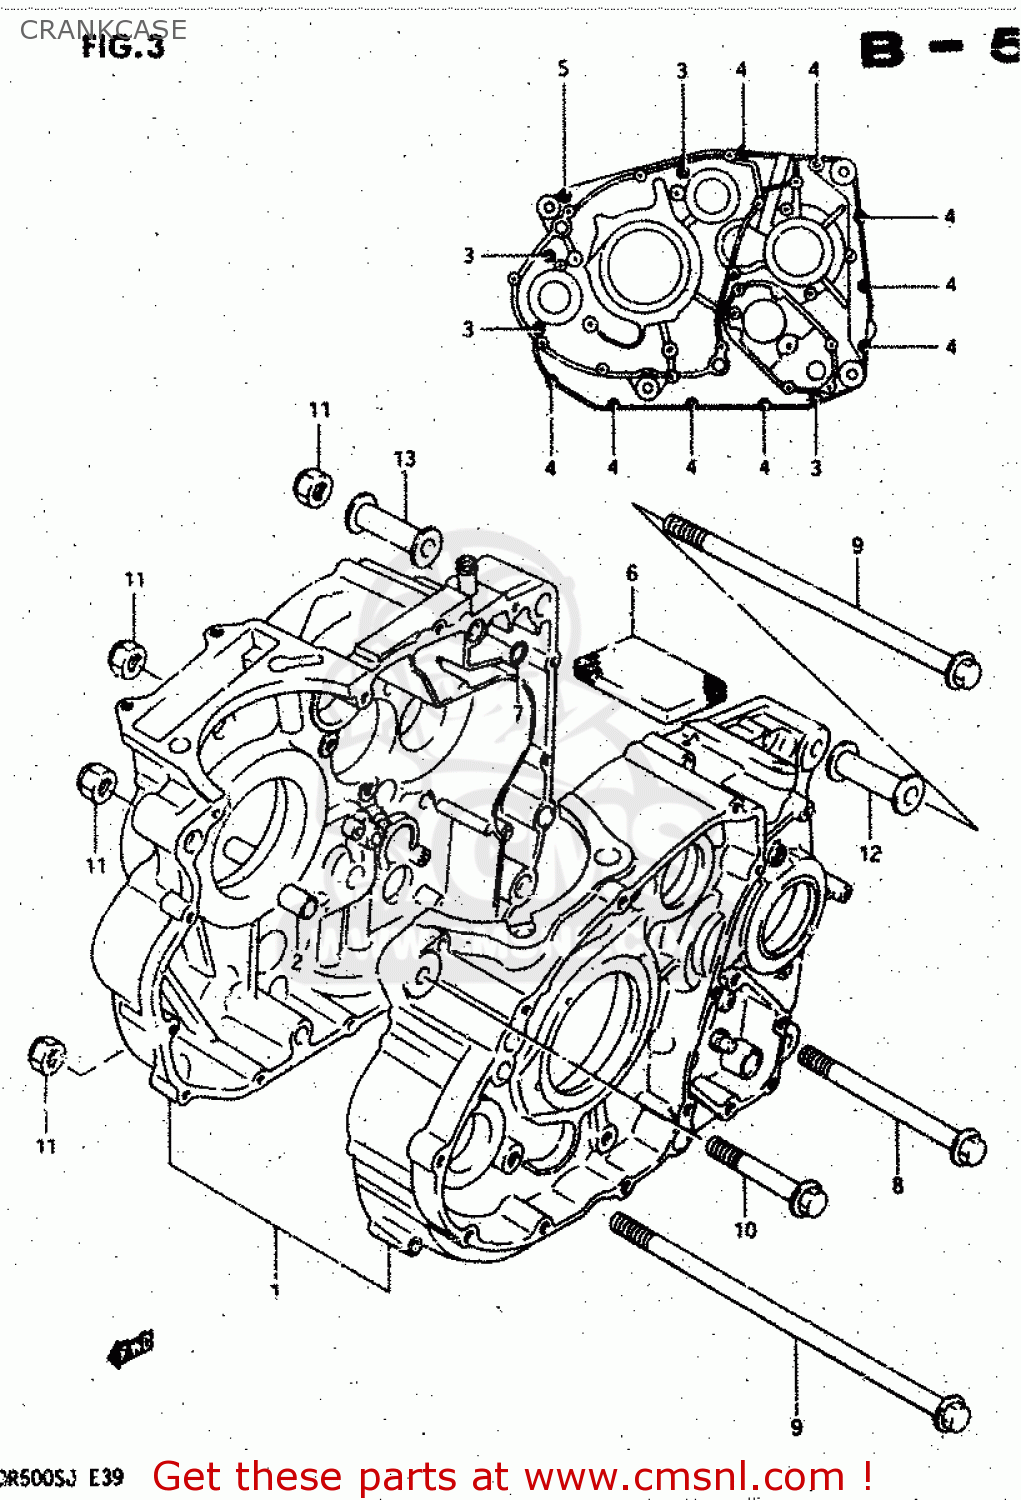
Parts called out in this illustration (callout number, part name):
1	CRANKCASE SET
2	PIN
3	BOLT (6X60)
4	BOLT 6X40
5	BOLT 6X30
6	HOSE
7	O-RING
8	BOLT(10X125)
9	BOLT
10	BOLT
11	NUT
12	SPACER,ENG MTG(L:55)
13	SPACER,ENG MTG,R(L:60)
